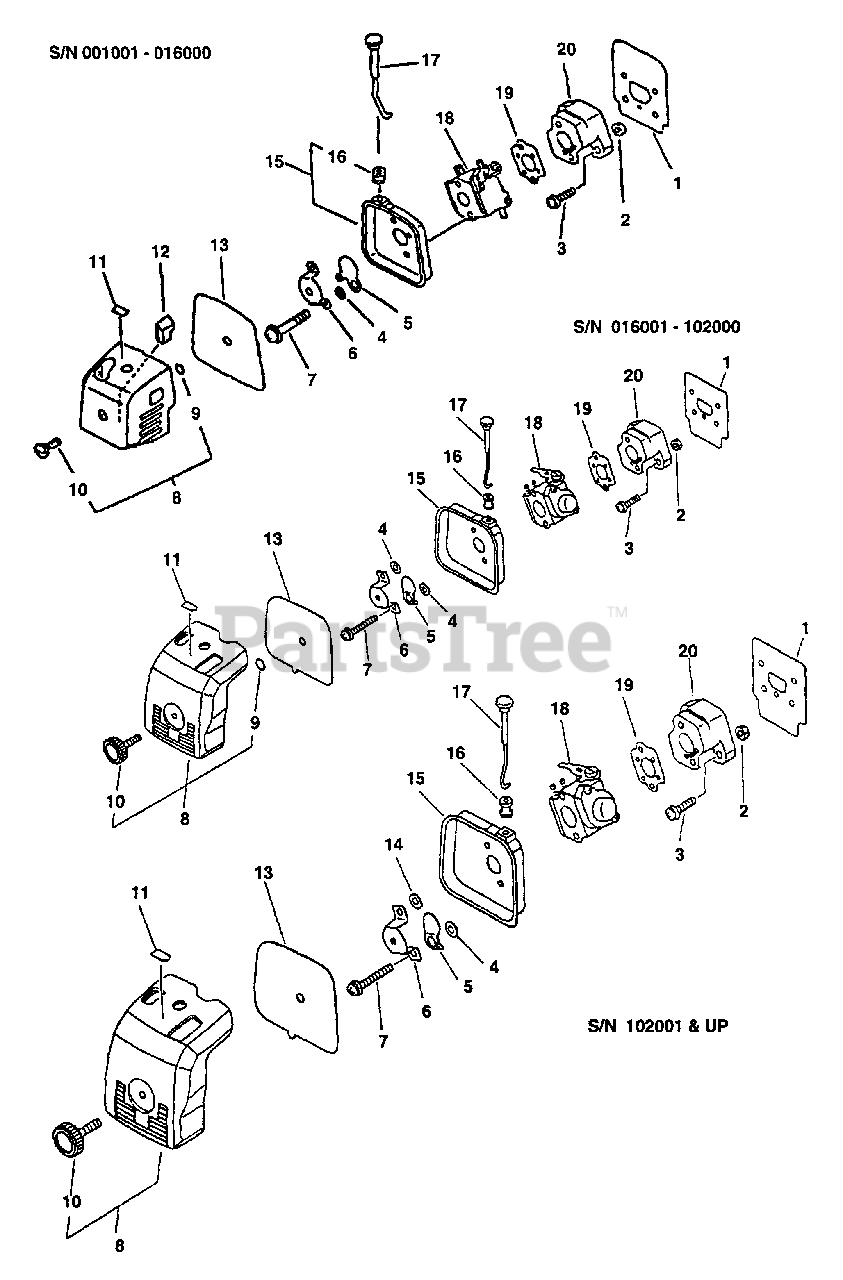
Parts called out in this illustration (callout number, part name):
1	SHIELD, INTAKE
3	SCREW - 5X20
4	WASHER - 5
5	SHUTTER, CHOKE
6	BRACKET, AIR CLEANER
6	PLATE, PREVENT
7	SCREW - 5X57
8	AIR FILTER COVER ASSY
9	O-RING - 4
9	O-RING - 3
10	SCREW
10	THUMBSCREW
11	LABEL - CHOKE
13	FILTER, AIR
13	FILTER, AIR - HEAVY DUTY
14	WASHER - 5
15	CASE, AIR FILTER
17	ROD, CHOKE
18	CARBURETOR C1U-K23A
18	CARBURETOR WT-424A
19	GASKET, INTAKE
20	INSULATOR, INTAKE
